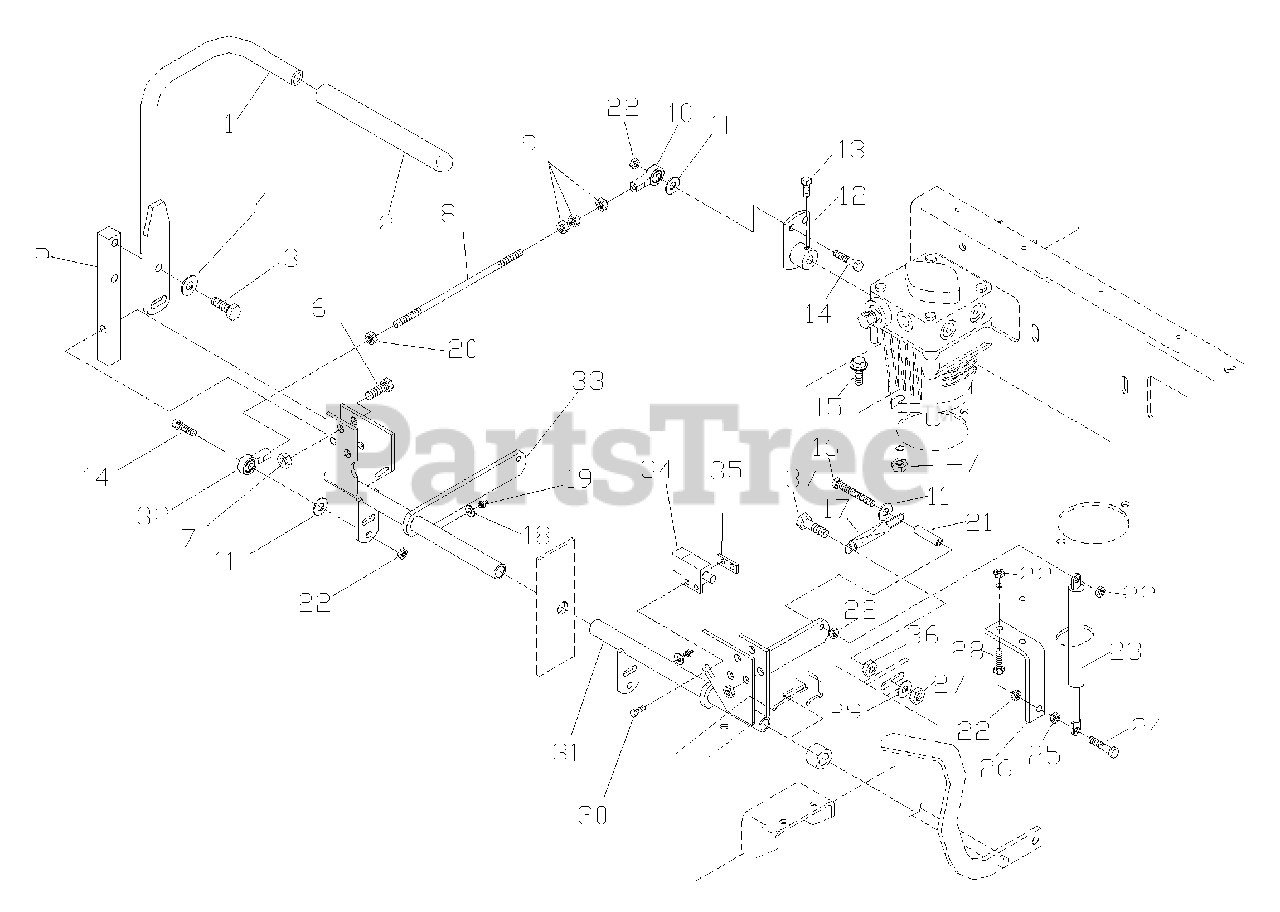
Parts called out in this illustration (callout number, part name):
1	CONT. LEVER
3	HCS 3/8C X 1
4	3/8 SPRING WASHER
5	ARM CONT SHAFT
6	HCS 3/8C X 1 1/2
7	NUT 3/8C CTR LOCK
8	PUMP CONTROL LINK
10	BALL JOINT RT
11	5/16 FLAT WASHER
12	PUMP LEVER
13	5/16C X 5/8 "V" POINT
14	HCS 5/16C X 1
15	HCS 3/8C X 1
16	TAPBOLT 5/16C X 2.25
17	REV DETENT SPRING
19	ZERK
20	NUT 5/16F LH
22	5/16C CTR LOCK
24	HCS 5/16C X 1.25
25	5/16C WHIZ NUT
26	BRACKET "L"
27	3/8C NYLOC
28	HCS 5/16C X 3/4
29	3/8 FLAT WASHER
30	SCREW #10-24 X 5/8
31	CONTROL WLDMT LEFT
32	BALL JOINT LH
33	CONTROL WLDMT RIGHT
35	TAPPED PLATE
36	3/8C WHIZ NUT
37	HCS 3/8C X 2
38	HOSE CLAMP
